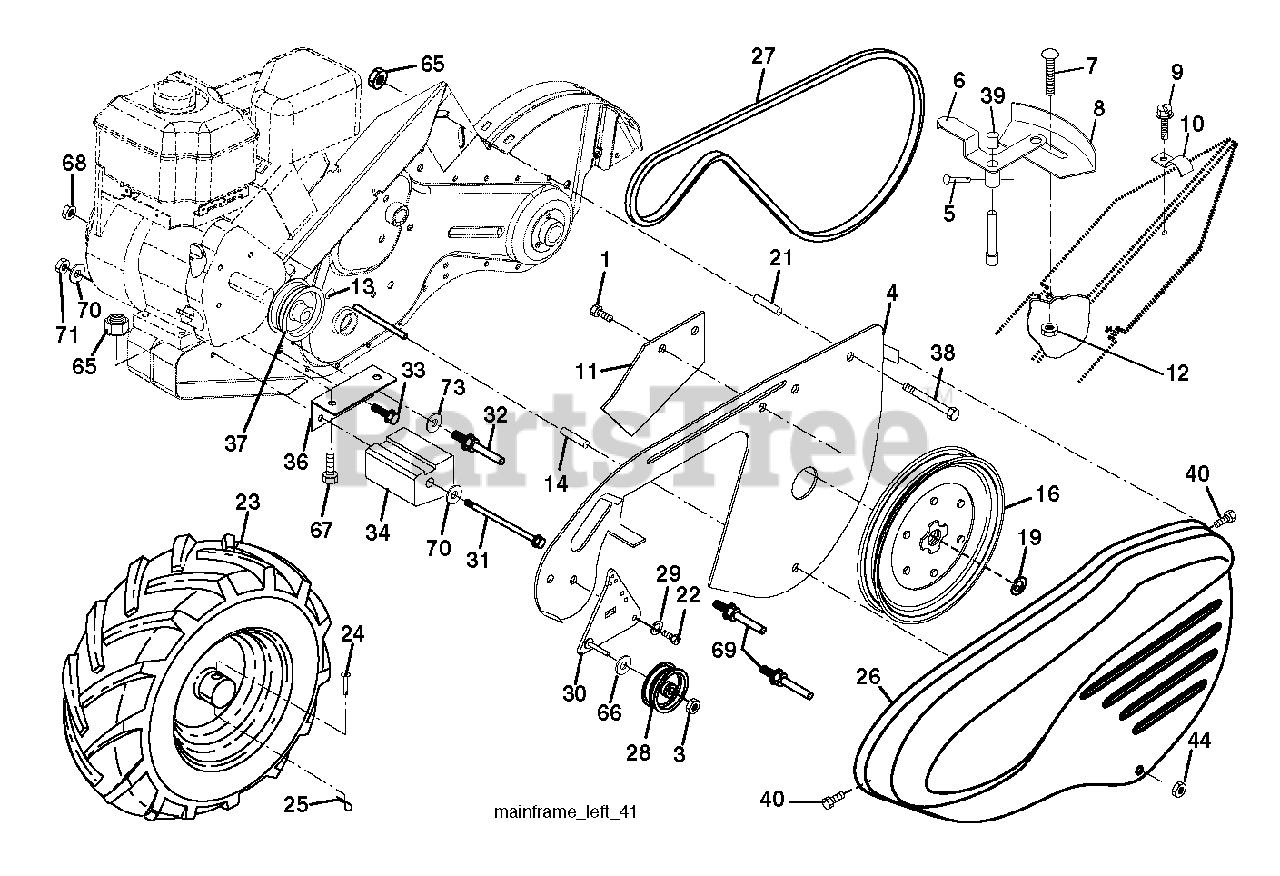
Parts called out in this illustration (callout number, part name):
1	SCREW.HEX.WASH.HD.TAPPING
3	LOCKNUT
5	PIN.SPIROL.FLARED
6	LEVER ASM CRT
9	TAPPING SCREW
10	CLIP.PLATED
11	GUARD.RT TILLER.CRT/DRT.CE
12	NUT
13	SET SCREW **
14	SPACER-SPLIT.327 X .42
16	SHEAVE, TRANSMISSION
19	RETAINING RING LT
23	WHEEL.ASM.16X4X8.DR.LH.417
24	RIVET
25	RETAINER M
27	V-BELT
28	PULLEY-IDLER TI
29	KLIP RING
30	Idler Assembly Bracket, Long
31	BOLT.FIN.HEX.3/8-16UNC X 11.5
32	SHIFT ARM CRT
33	BOLT
34	COUNTERWEIGHT.LH
37	ENGINE PULLEY
38	BOLT
39	CAP.PLUNGER.BLACK
40	SCREW.HEX.WSH.SLT.#10-24X.50
44	NUT.71038.31-18.HEX.NYLOCK
65	LOCKNUT-FLANGE 5/16-18
67	BOLT, HEX 5/16-18X1-3/4
69	KEEPER.BELT.ENGINE
71	LOCKNUT
73	WASHER
